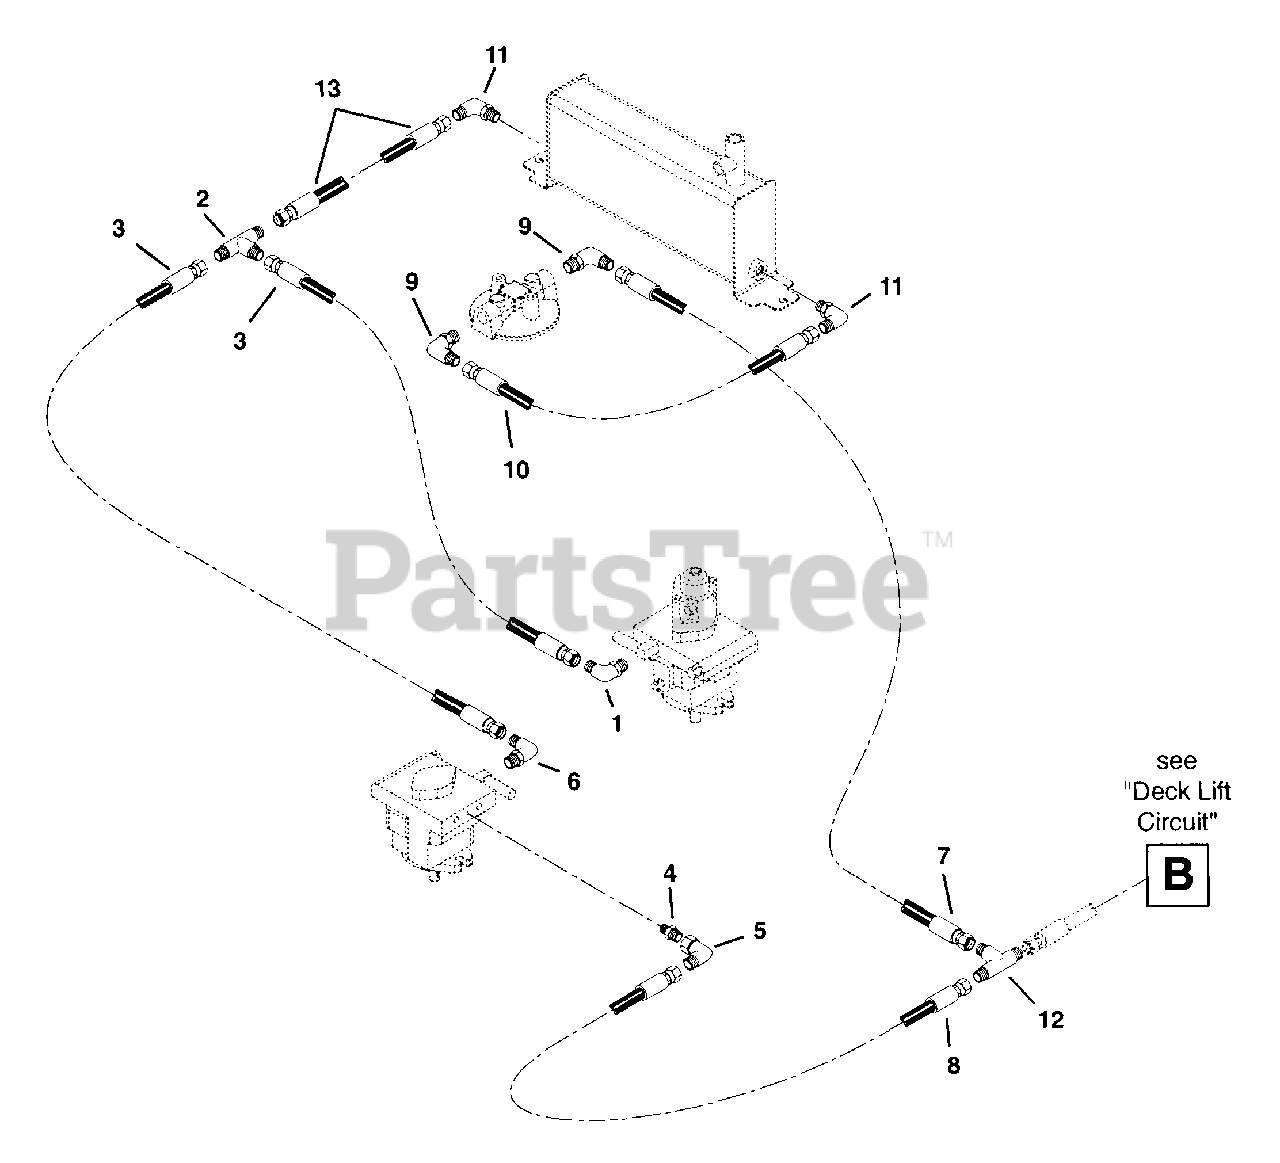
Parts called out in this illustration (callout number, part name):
1	Adapter
2	Adapter-Tee .56-18
3	Hose-Hydraulic Valve to Tank
5	Adapter
6	Adapter
7	Hose-Hydraulic Valve to Tank
8	Hose-Pump to Tee
9	Adapter
10	Hose-Hydraulic Valve to Tank
11	Adapter
12	Adapter-Tee .56-18
13	Hose-Pump to Tee
